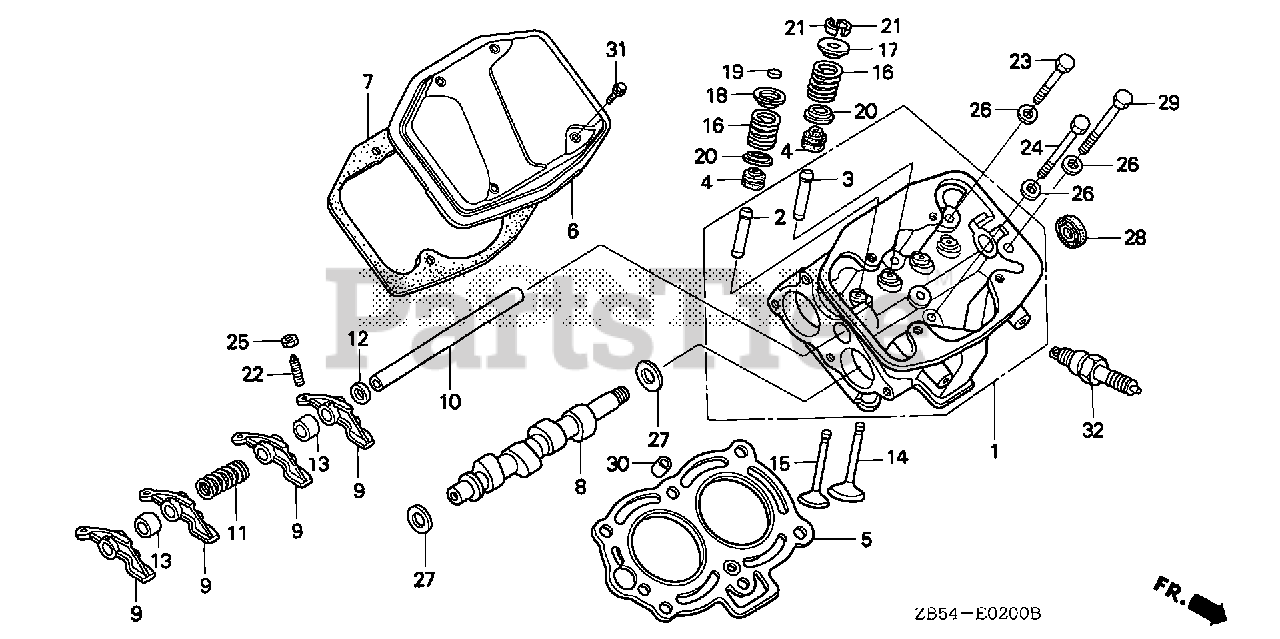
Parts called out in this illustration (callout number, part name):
1	CYLINDER HEAD
2	GUIDE, EX. VALVE
3	GUIDE, VALVE (OS)
4	SEAL, VALVE STEM
5	GASKET, CYLINDER HEAD
6	COVER, CYLINDER HEAD
7	GASKET, CYLINDER HEAD COVER
8	CAMSHAFT
9	ARM, VALVE ROCKER
10	SHAFT, VALVE ROCKER ARM
11	SPRING, VALVE ROCKER ARM
12	COLLAR A, VALVE ROCKER ARM
13	COLLAR B, VALVE ROCKER ARM
14	VALVE, IN.
15	VALVE, EX.
16	SPRING, VALVE
17	RETAINER, VALVE SPRING
18	RETAINER, VALVE SPRING
19	ROTATOR, VALVE
20	SEAT, VALVE SPRING
21	COTTER, VALVE
22	SCREW, TAPPET ADJ.
23	BOLT, HEAD (8X70)
24	BOLT, HEX. (8X55)
25	NUT, TAPPET ADJ.
26	WASHER, HEAD (8MM)
27	WASHER, THRUST (16MM)
28	OIL SEAL (16X28X6)
29	BOLT, HEX. (8X100)
30	PIN A, DOWEL (10X16)
31	BOLT, FLANGE (6X20)
32	SPARK PLUG (BPR4HS) (NGK)
